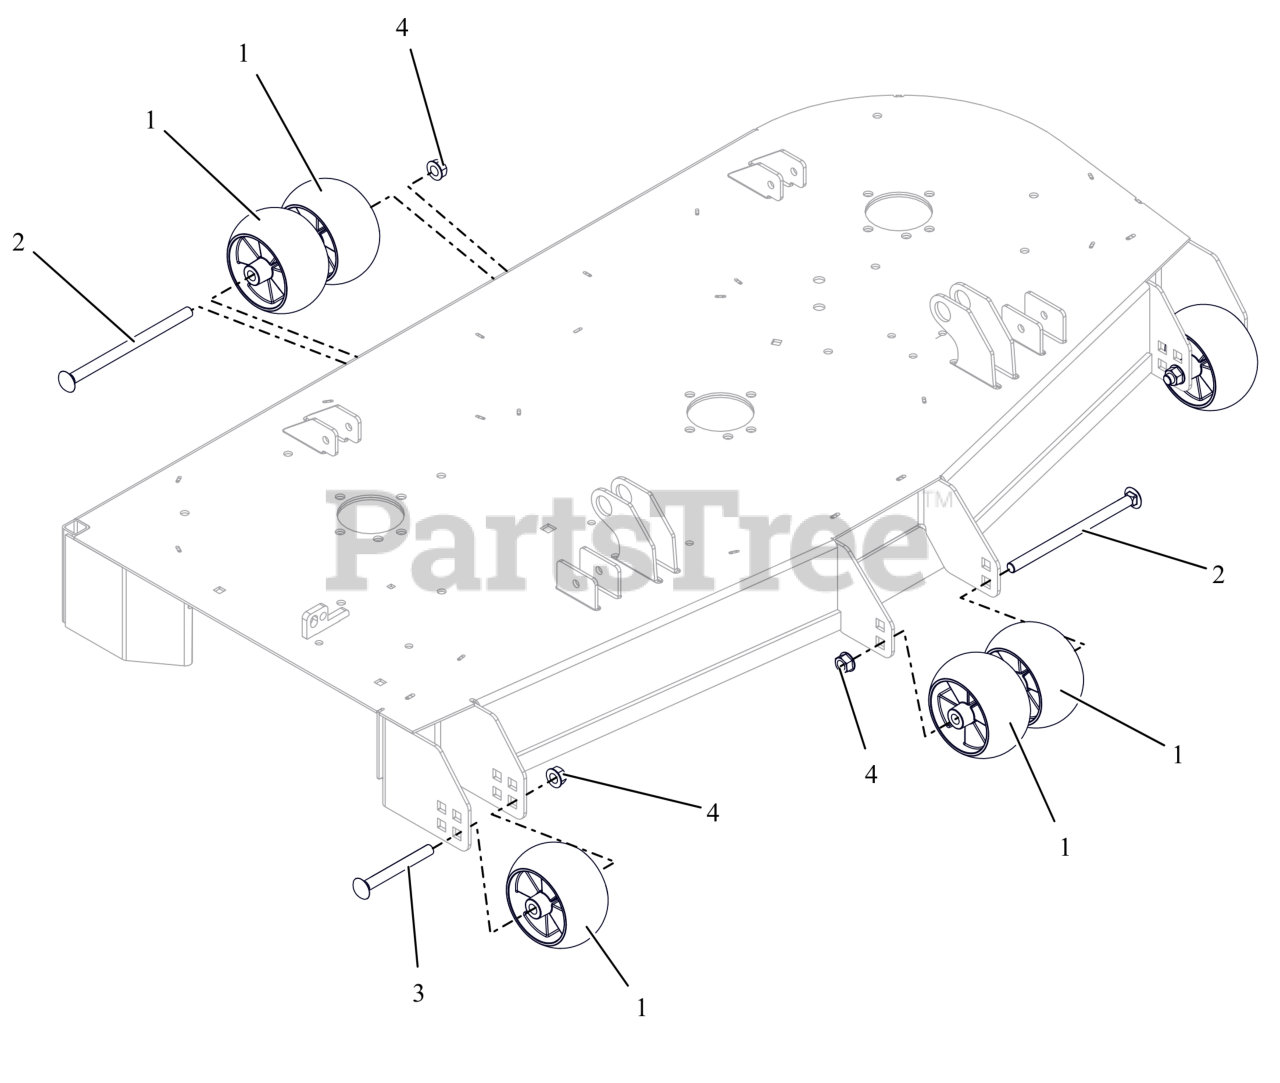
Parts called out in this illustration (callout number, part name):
1	WHEEL, ANTI SCALP - 5X3 CTR W/RIBS
2	BLT-RHSN .50-13X8.00 G5 ZCC NS
3	BLT-RHNS .50-13X4.50 G5 ZCC NS
4	NUT-LK-CTR-FLG .500-13 GG ZCC
